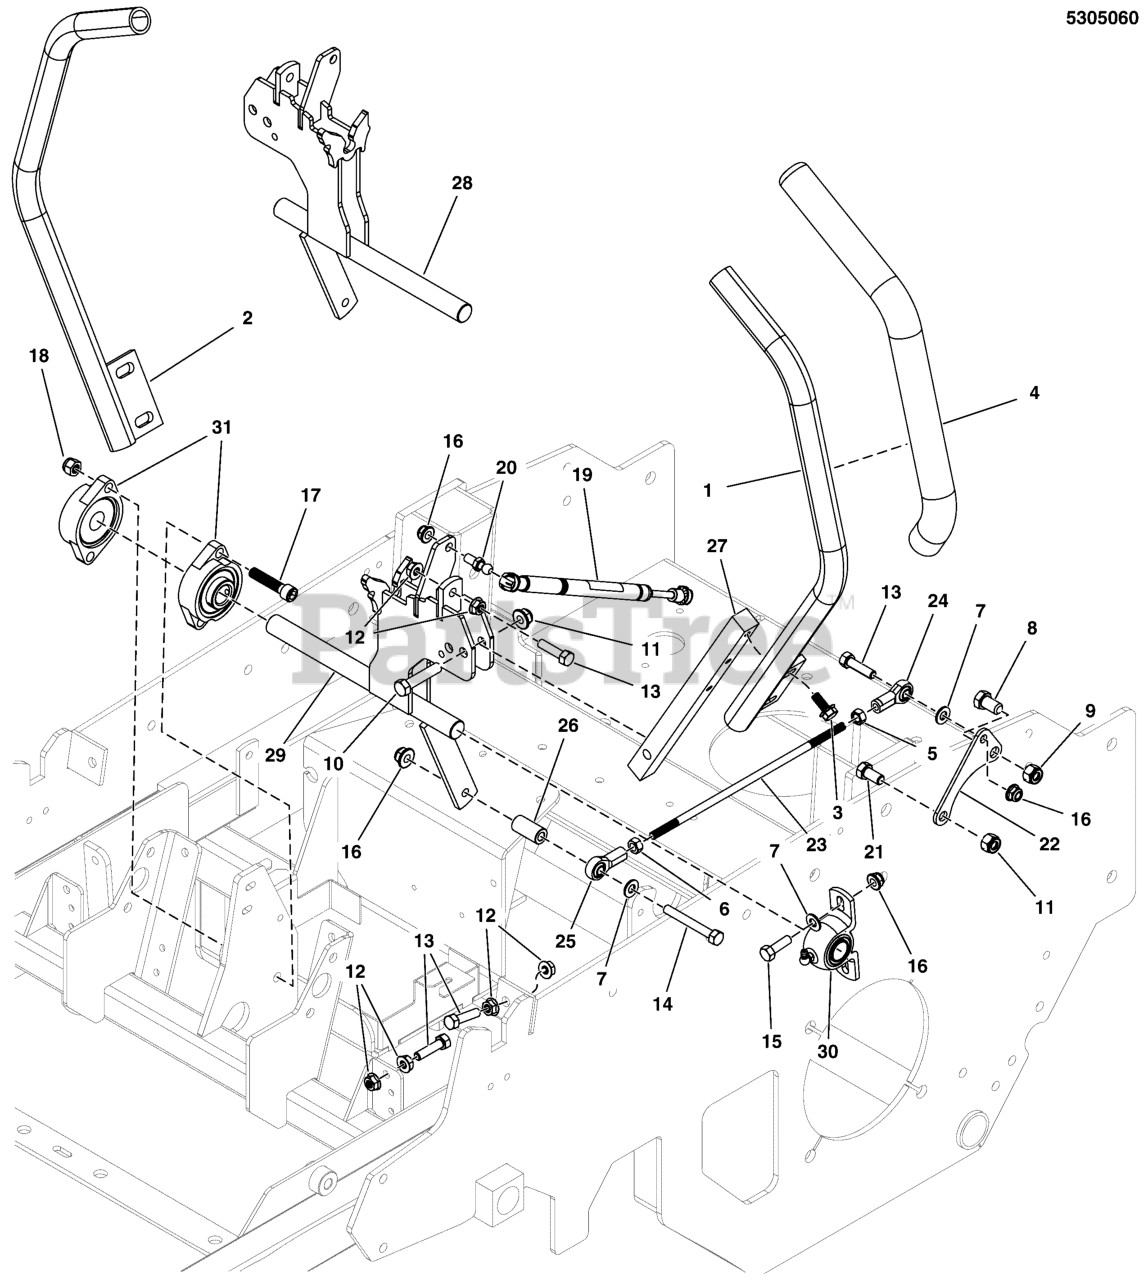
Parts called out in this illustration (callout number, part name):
1	WELD,HANDLE MOTION CNTRL,17.0,1.0,LH,BLK
2	WELD,HANDLE MOTION CNTRL,17.0,1.0,RH,BLK
3	SCREW, 5/16-18x0.750, GR5, WHIZ-LOCK, ZC
4	GRIP, FOAM, 1" ID, 16" LONG
5	NUT, 5/16-24 HEX
6	NUT, 5/16-24 HEX, LH
7	WASHER, 5/16" SAE
8	BOLT, 7/16-14 X 3/4, GD 5 CZ
9	NUT, 7/16-14 HEX TOP LOCK
10	BOLT, 3/8-16 X 1-3/4" GD5 CZ
11	NUT, 3/8-16 HEX NYLOCK FLANGE
12	NUT, 5/16-18 HEX SERRATED FLANGE (SMALL)
13	BOLT, 5/16-18 X 1-1/4 GD5 CZ
14	BOLT, 5/16-18 X 2-1/2 GD5 CZ
15	BOLT, 5/16-18 X 1 GD5 CZ
16	NUT, 5/16-18 HEX NYLOCK FLANGE
17	BOLT, 3/8-16 X 1-3/4, SHCS, CZ
18	NUT, 3/8-16 HEX NYLON LOCK
19	DAMPENER, CONTROL,#(P6709/P3610)
20	BALL STUD, 5/16 X .50,# PC-477-2)
21	BOLT, 3/8-16 X 3/4" GD5 CZ
22	PLATE, HYDRO CONNECTOR - BLK
23	ROD, HYDRO LINKAGE
24	BALL JOINT 5/16-24 RH FEMALE BRONZE RACE
25	BALL JOINT 5/16-24 LH FEMALE BRONZE RACE
26	SPACER, .33 X .63 X 1.25, PM, CZ
27	MOUNT, CONTROL ARM - BLK
28	WELD, CONTROL SHAFT, LH 150/160 - BLK
29	WELD, CONTROL SHAFT, RH 150/160 - BLK
30	BEARING, 3/4" PILLOW BLOCK
31	BEARING, FLANGE
